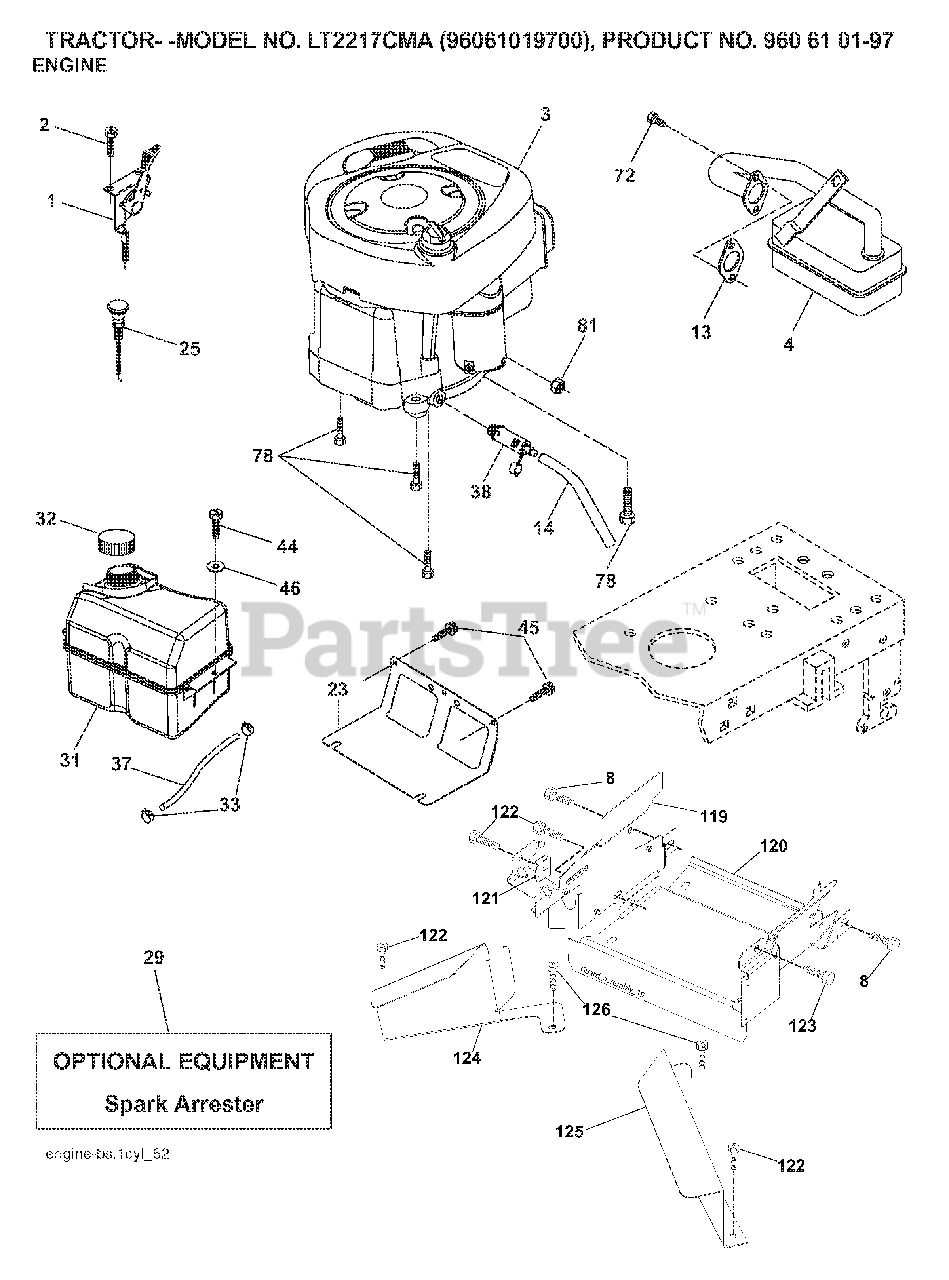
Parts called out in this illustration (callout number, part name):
1	CONTROL TH/CH FLAG
2	SCREW
8	BOLT, 5/16-18 X 1 3/4
13	REPL BY 532 27 22-93
14	TUBE, DRAIN OIL ASM.
23	SHEILD.BROWNING.DBR.GUARD
29	ARRESTER SPARK (OPTIONAL)
31	TANK FUEL
32	FUEL CAP
33	HOSE CLAMP
37	LINE.FUEL.20
38	PLUG DRAIN OIL EASY
44	SCREW HEXWSHR 1/4-20X3/4
45	SCREW, 3/8-16X3/4
72	SCREW.SOCKET HD.5/16-1
78	SCREW.3/8-16
81	NUT
122	SCREW.1/4-20X5/8
123	SCREW, 5/16-18 X 1/2
126	SCREW
